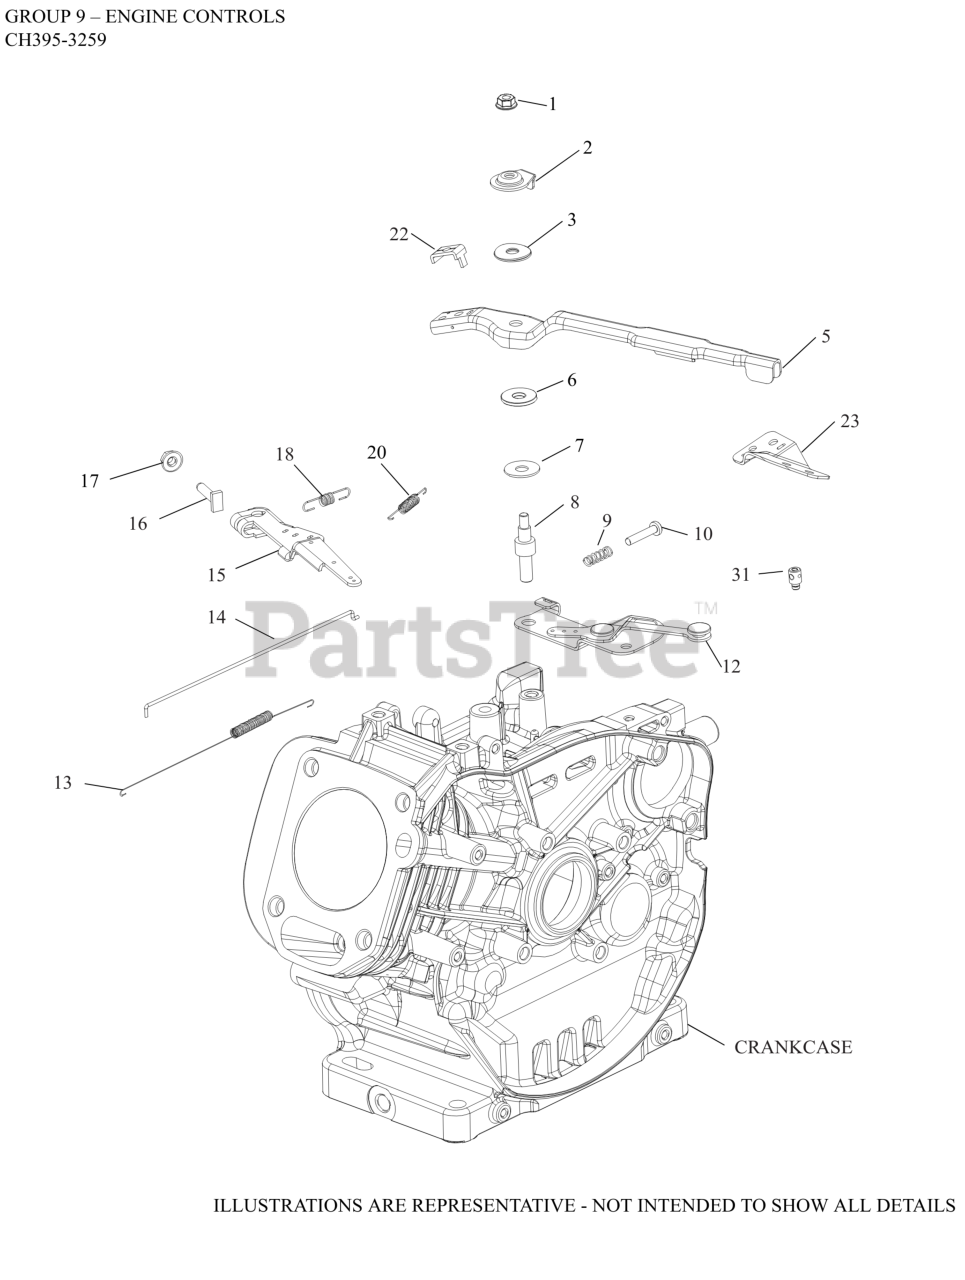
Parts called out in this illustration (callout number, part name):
1	NUT, HEX FLANGE LOCK (M6)
2	WASHER, CONTROL LEVER
3	WASHER, SPRING
5	CONTROL LEVER ASSEMBLY
6	WASHER, NYLON CONTROL LEVER
7	WASHER, FLAT
8	STUD, CONTROL LEVER
9	SPRING, COMPRESSION
10	SCREW, SPEED ADJUSTING
12	BRACKET, CONTROLS ASSY
13	SPRING, LINKAGE
14	LINKAGE, GOVERNOR
15	KIT, GOVERNOR LEVER
16	SCREW, RECTANGLE HEAD (M6)
17	NUT, HEX FLANGE (M6) - USE 14 100 16-S
18	SPRING, GOVERNOR
20	SPRING, THROTTLE RETURN
22	CLAMP, CABLE
23	BRACKET, BOWDEN CABLE ASSY
31	KIT, CABLE CLAMP
